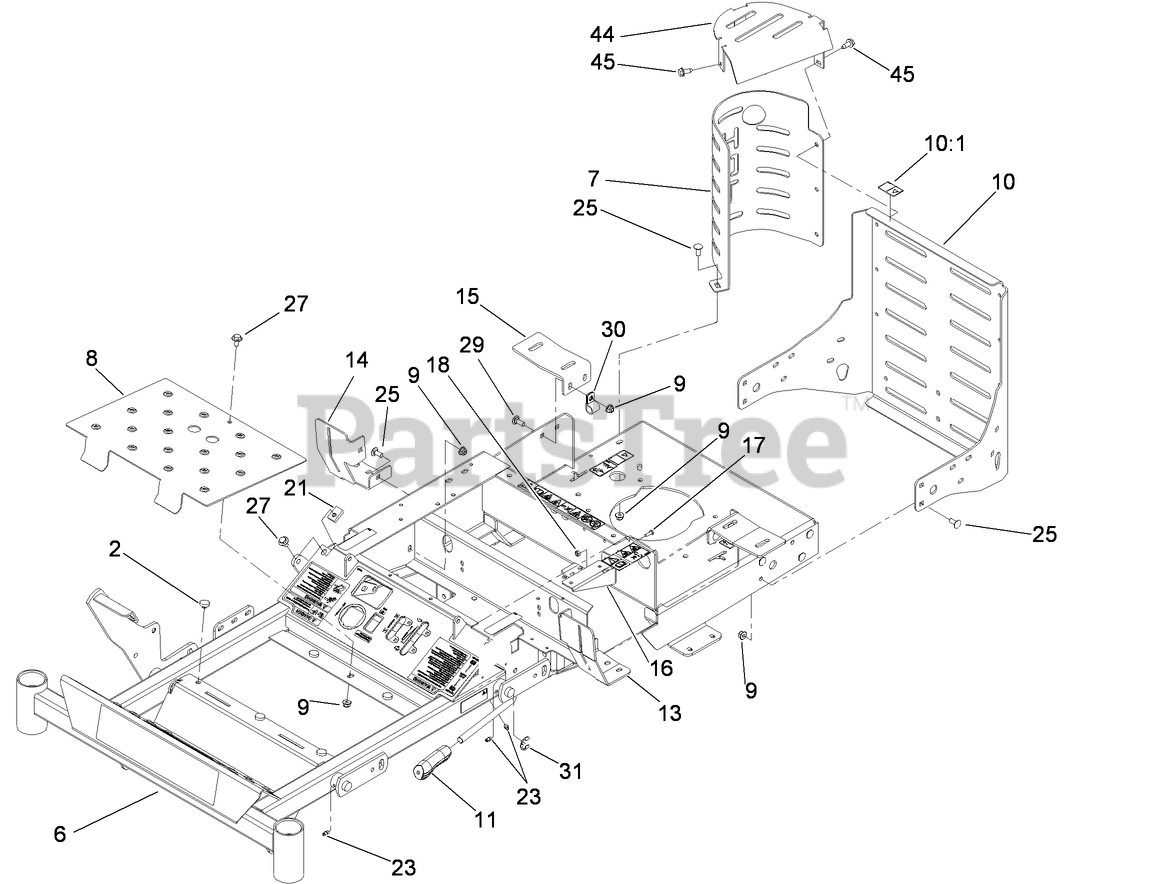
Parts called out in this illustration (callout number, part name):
2	BUMPER
6	FRAME ASM
7	GUARD-MUFFLER
8	PLATE-FLOOR
9	NUT-HF, NI
10	REAR GUARD ASM
10:1	DECAL-SURFACE, HOT
11	GRIP-LEVER, BRAKE
13	MOUNT-TANK, FUEL (LH)
14	MOUNT-TANK, FUEL (RH)
15	BRACKET-FUEL TANK, REAR
16	BRACKET-FUSEBLOCK
17	SCREW-PPH
18	NUT-LOCK, NI
21	STOP-MOTION
23	FITTING-GREASE
25	SCREW-CARR
27	SCREW-HHF
29	SCREW-CARR
30	CLIP-LOOM
31	E-RING
44	SHIELD-HEAT
45	SCREW-HWHTF
